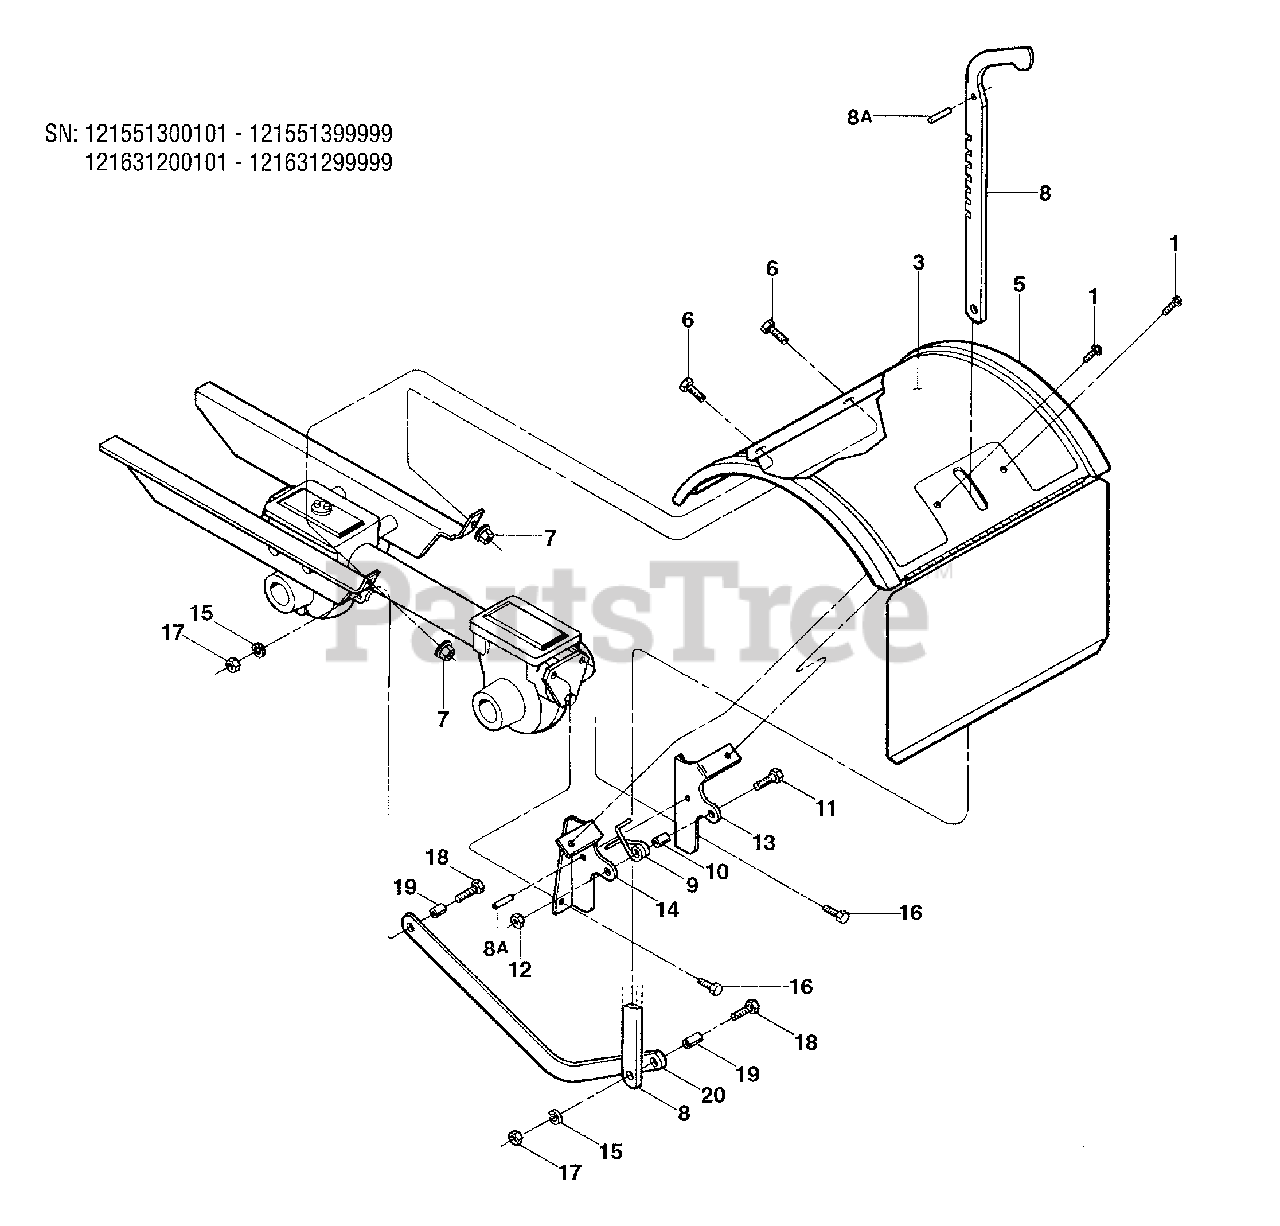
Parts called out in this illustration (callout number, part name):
1	Bolt-Fl. Hd., Self-Tap, 1/4-20 x 1/2"
3	Decal-Hood
5	Tine Hood
6	Bolt-Hex Hd., 5/16-18 x 1/2"
7	Nut-Flange Lock, 5/16-18
8	Depth Regulator Lever
8A	Spirol Pin
9	Spring-Depth Regulator
10	Spacer
11	Bolt-Hex Hd., 1/4-20 x 1"
12	Locknut-Hex Hd., 1/4-20
13	Bracket-Hood, Right Hand
14	Bracket-Hood, Left Hand
15	Lockwasher, 5/16"
16	Bolt-Flanged Hd., 5/16-18 x 1"
17	Nut-Hex Hd., 5/16-18
18	Bolt-Hex Hd., 5/16-18 x 1-1/4"
19	Bushing-Drag Bar
20	Drag Bar
